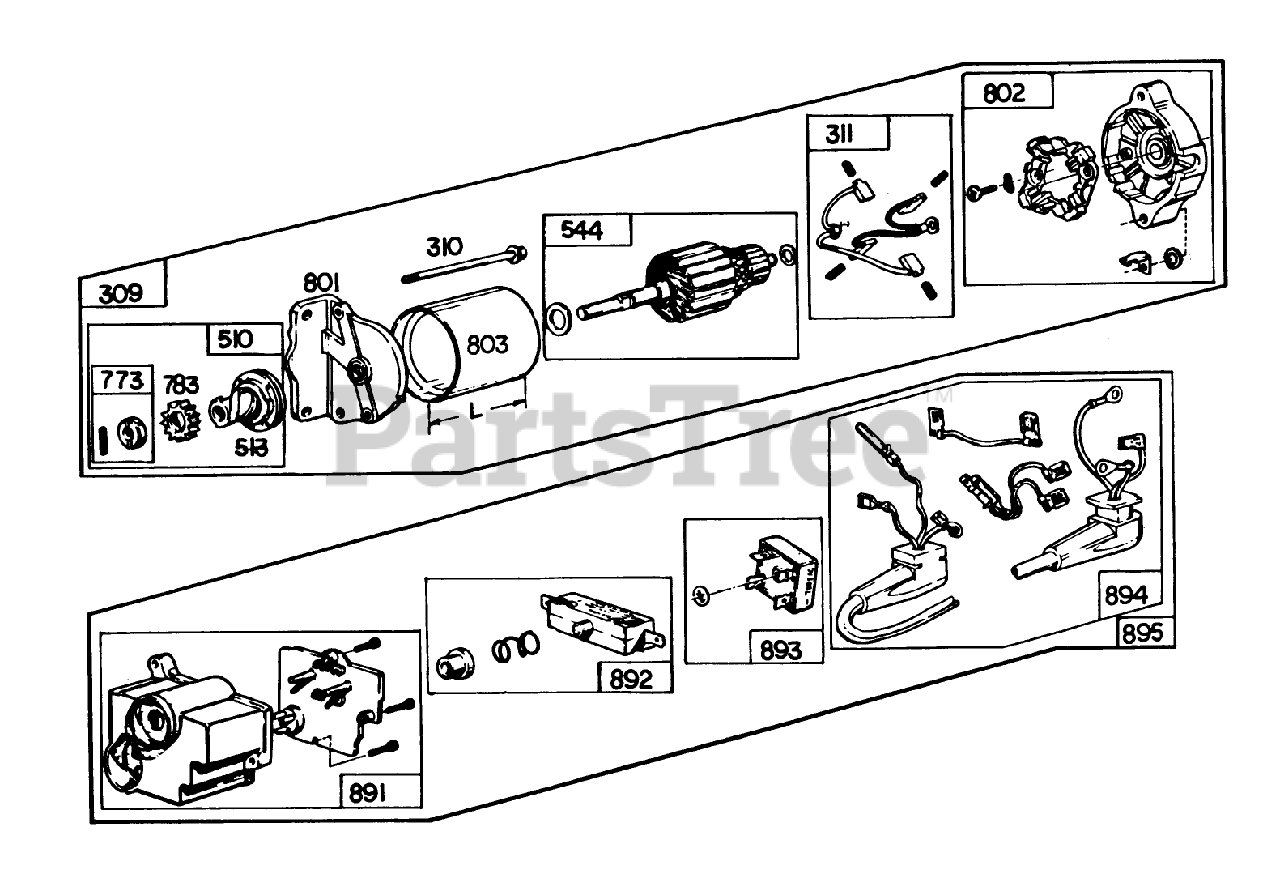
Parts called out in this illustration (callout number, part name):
309	Motor Drive Assembly
310	Thru Bolt Assembly
311	Brush Assembly
510	Drive Assembly
513	Clutch Assembly
544	Armature Assembly
773	Gear-Starter
801	Drive End Cap Assembly
802	Comm. End Cap Assembly
803	Housing Assembly
891	Housing Group
892	Switch Group
893	Rectifier
894	Lead Group
895	Control Group
